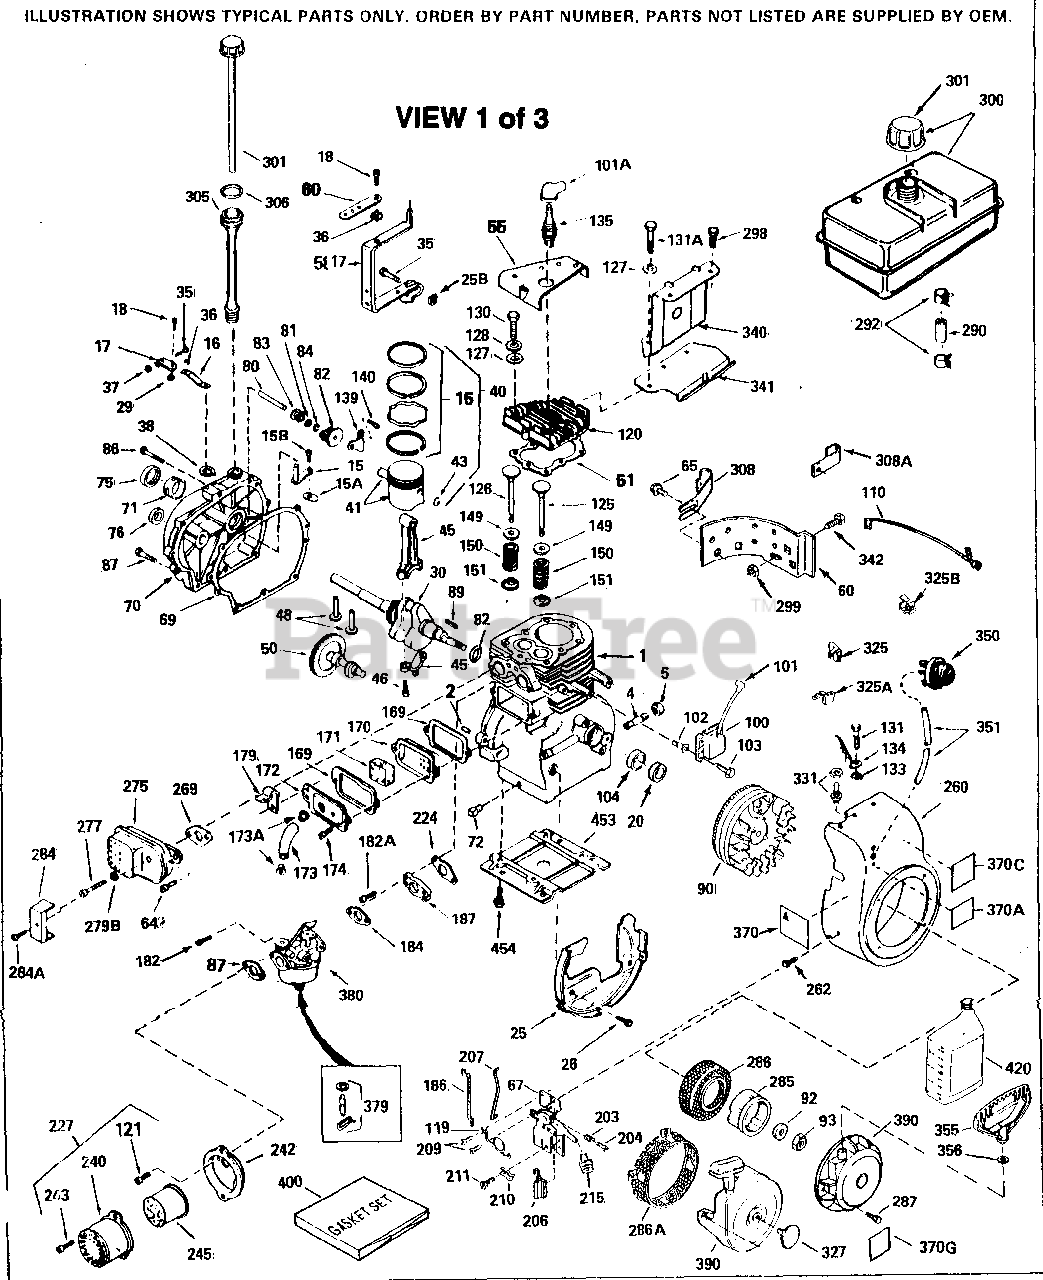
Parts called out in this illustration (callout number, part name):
1	"Cylinder (Incl. 2, 20 & 72)
2	Dowel Pin
15	Governor Rod (Incl. 15A & 15B)
15A	Governor Yoke
15B	Screw, 6-40 x 5/16"
16	Governor Lever
16A	Governor Bracket
18	Screw, 8-32 x 5/16"
20	Oil Seal
25	Blower Housing Baffle
26	Screw, 1/4-20 x 5/8"
30	Crankshaft
35	Screw, 10-32 x 3/4"
36	Lock Washer #8
37	Lock Nut, 10-32
38	Retaining Ring
40	Piston, Pin & Ring Set (Std.)
40	Piston, Pin & Ring Set (.010" OS)
40	Piston, Pin & Ring Set (.020" OS)
41	Piston & Pin Ass'y. (Std.) (Incl. 43)
41	Piston & Pin Ass'y. (.010" OS) Incl. 43
41	Piston & Pin Ass'y. (.020" OS) Incl. 43
42	Ring Set (Std.)
42	Ring Set (.010" OS)
42	Ring Set (.020" OS)
43	Piston Pin Retaining Ring
45	Connecting Rod Ass'y. (Incl. 46)
46	Connecting Rod Bolt
48	Valve Lifter
50	Camshaft (MCR)
60	Blower Housing Extension
65	Screw, 10-24 x 1/2"
69	* Cylinder Cover Gasket
70	Cylinder Cover (Incl. 71, 75 & 80)
71	Crankshaft Bushing
72	Oil Drain Plug (Sq. hd., 1/4-18)
75	Oil Seal
80	Governor Shaft
82	Governor Gear Ass'y. (Incl. 81)
83	Governor Spool
84	Retaining Ring
86	Screw, 1/4-20 x 1-1/4"
87	Screw, 1/4-20 x 1-3/4"
89	Flywheel Key
90	Flywheel
92	Belleville Washer
93	Flywheel Nut
100	Solid State Ignition
102	Solid State Mounting Stud
103	Screw, Torx T-15, 10-24 x 1"
110	Ground Wire
119	* Cylinder Head Gasket
120	Cylinder Head (Incl. 3 of 130)
125	Exhaust Valve (Std.)(Incl. 151)
125	Exhaust Valve (1/32" OS) (Incl. 151)
126	Intake Valve (Std.) (Incl. 151)
126	Intake Valve (1/32" OS)(Incl. 151)
128	Belleville Washer
130	Screw, 5/16-18 x 2-1/2"
135	Resistor Spark Plug - RJ17LM
139	Governor Gear Bracket
140	Screw, Torx T-25, 10-24 x 1/2"
149	Valve Spring Cap
150	Valve Spring
151	Valve Spring Keeper
169	* Valve Cover Gasket
170	Breather Body
171	Breather Element
172	Valve Cover
173	Breather Tube
174	Screw, 10-24 x 1/2"
178	Nut & Lock Washer 1/4-28
182	Screw, 1/4-28 x 1-1/8"
184	* Carburetor To Intake Pipe Gasket
200	Control Bracket
207	Throttle Link
210	Conduit Clip
211	Screw, 10-32 x 3/8"
224	* Intake Pipe Gasket
227	Air Cleaner Elbow
238	Screw, 10-32 x 1-1/8"
239	Air Cleaner Gasket
240	Air Cleaner Body
242	Air Cleaner Bracket
243	Screw, 8-32 x 3/8"
245	Air Filter (Paper) also available in Packaged Part #740029B
260	Blower Housing
262	Screw, T-40, 5/16-24 x 21/32"
265	Cylinder Head Cover
272	Screw, 5/16-18 x 3/4"
273	Carburetor Flange
275	Muffler
285	Starter Cup
287	Screw, 8-32 x 21/64"
291	Fuel Line
292	Fuel Line Clamp
305	Oil Fill Tube
307	"O" Ring
308	Fill Tube Clip
310	Dipstick
325	Wire Clip
327	Starter Plug
342	Screw, T-30, 1/4-20 x 1/2"
345	Heat Baffle
370	Instruction Decal
370A	Lubrication Decal
380	Carburetor (Incl. 184)
390	Rewind Starter
400	* Gasket Set (Incl. items marked PK in notes) Incl. part #'s 27272A (2), 278 96A (2), 27913A (1), 27915A (2), 2893 8C (1), 29673 (1), 30684 (1), 31688A (1), 33355A (1), 35865 (1)
450	Pre-Cleaner Kit
451	Pre-Cleaner Bag Spring
452	Air Filter
453	Engine Mounting Base
454	Screw, 5/16-18 x 3/4"
